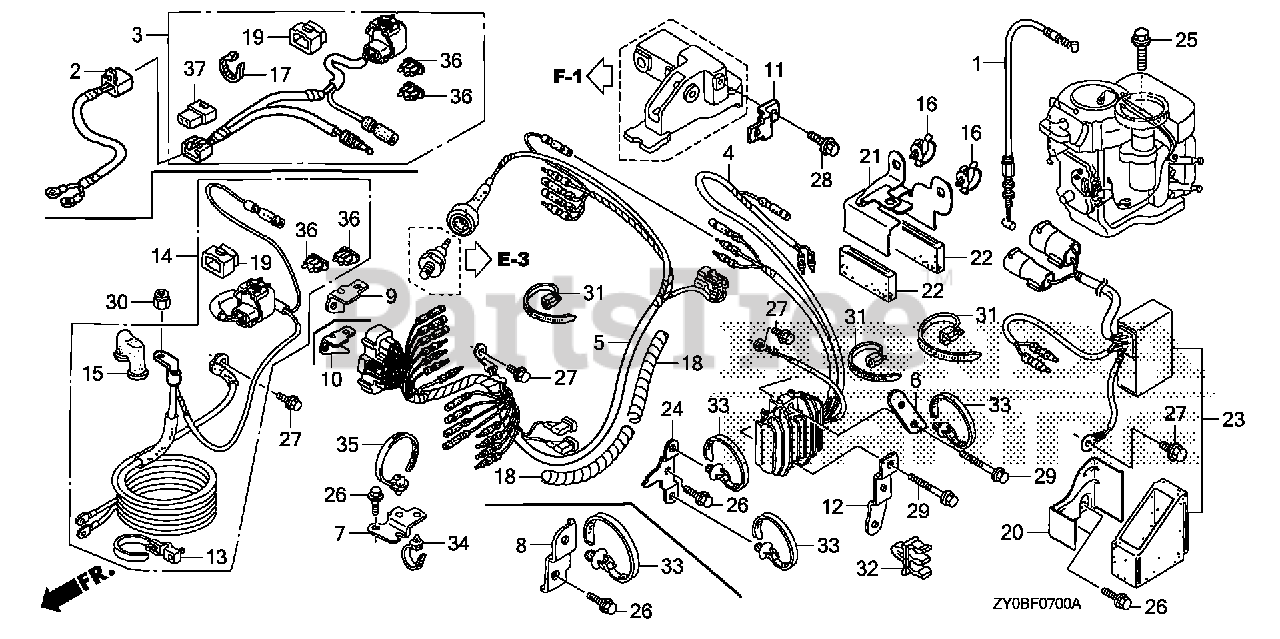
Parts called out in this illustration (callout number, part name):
1	CABLE, NEUTRAL STARTING
4	RECTIFIER ASSY., REGULATOR
5	WIRE HARNESS ASSY. (SELF STARTER)
6	BRACKET, CLIP F
7	BRACKET, STARTER CABLE
10	BRACKET, FUSE CASE (PT)
12	BRACKET, E-CLIP
13	BAND, WIRE
14	CABLE ASSY., STARTER (PT)
15	COVER, MAGNETIC SWITCH TERMINAL
16	CLAMP, WIRE
18	TUBE, SPIRAL A
19	COVER ASSY., FUSE (20A)
20	BRACKET, RELAY (PT)
21	BRACKET, CONNECTOR A
22	GROMMET, CONNECTOR
23	RELAY ASSY., POWER TILT
24	BRACKET, HARNESS CLIP
25	BOLT, FLANGE (6X20)
26	BOLT, FLANGE (6X14) (CT200)
27	BOLT, FLANGE (6X12)
29	BOLT, FLANGE (6X26) (CT200)
30	NUT, LOCK (6MM)
31	TIE, CABLE
32	CLIP, FUEL TUBE
33	CLIP, HARNESS BAND (151.5MM) (NATURAL)
34	BAND, WIRE HARNESS (123.5MM) (BLUE)
35	BAND, WIRE HARNESS (93.5MM) (WHITE)
36	FUSE, BLADE (20A)
